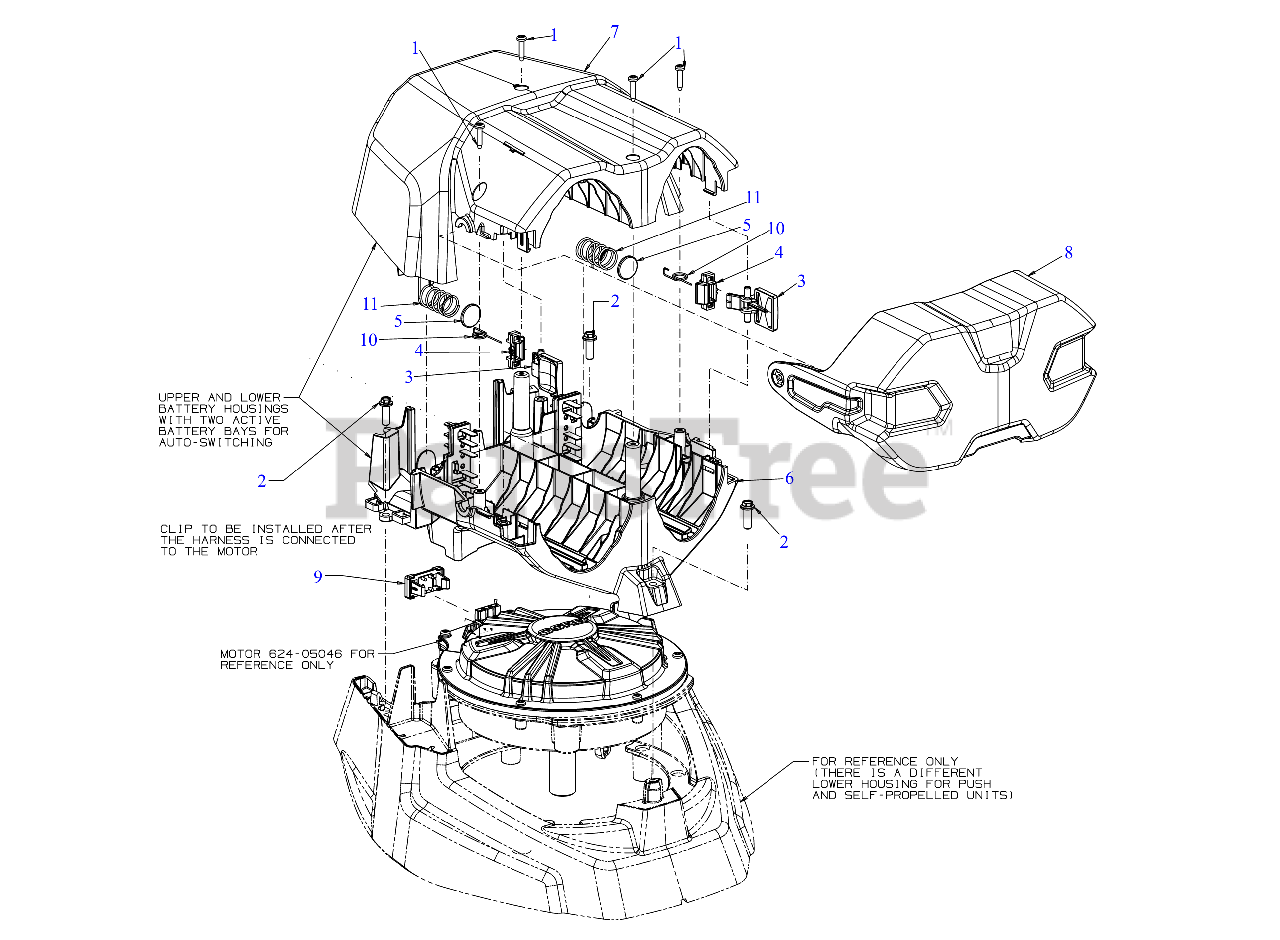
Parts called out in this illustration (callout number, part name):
1	SCREW 7-18X.75:T20
2	SCREW 1/4 x .750
3	LATCH BATTERY ASSEMBLY
4	BATTERY RELEASE LATCH
5	BATTERY RELEASE SPRING CAP
6	MIDDLE BATTERY HOUSING
7	DUAL BATTERY UPPER HOUSING
8	BATTERY HOUSING LID
9	RETAINING CLIP
10	SPRING TRIG
11	BATTERY RELEASE SPRING
